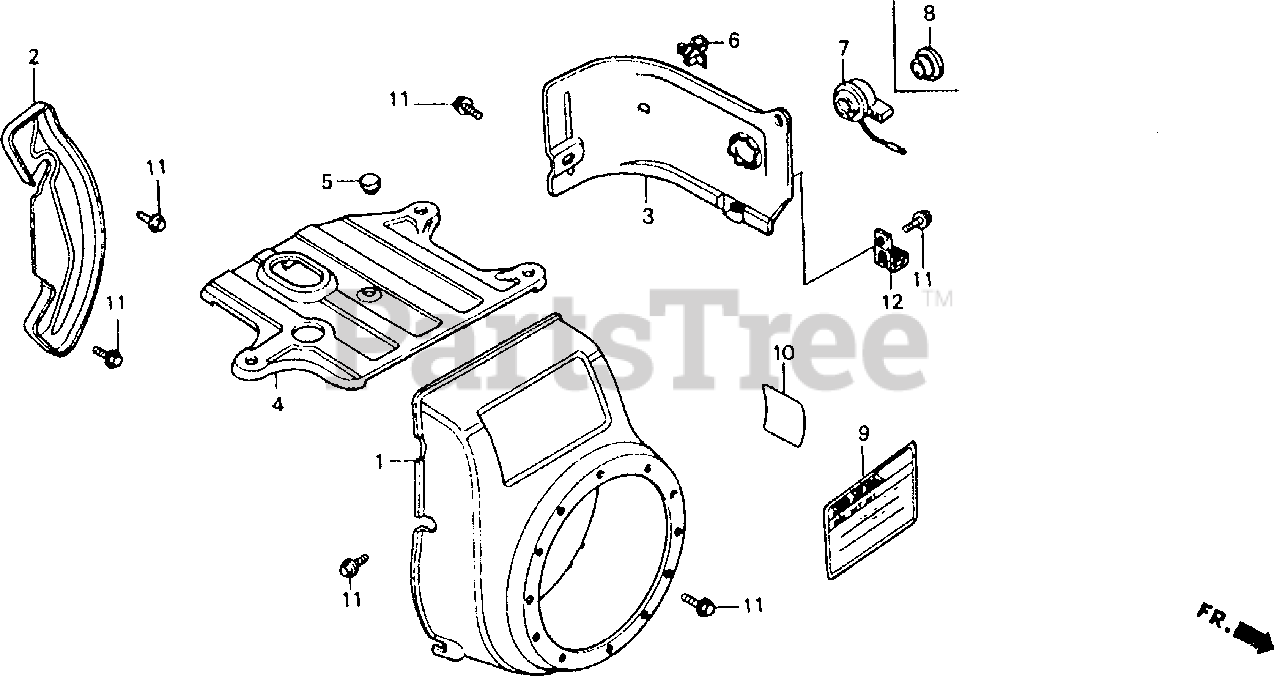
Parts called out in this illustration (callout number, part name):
1	COVER, FAN *R8* (BRIGHT RED)
2	PLATE, SIDE
3	SHROUD
4	COVER, TOP
5	GROMMET, TOP COVER
6	CLIP, IGNITION WIRE (8MM)
7	SWITCH ASSY., ENGINE STOP
9	EMBLEM (ENGLISH/FRENCH)(SPANISH)
10	MARK, OIL CAUTION
11	BOLT, FLANGE (6X12) (CT200)
12	CLIP, CABLE
